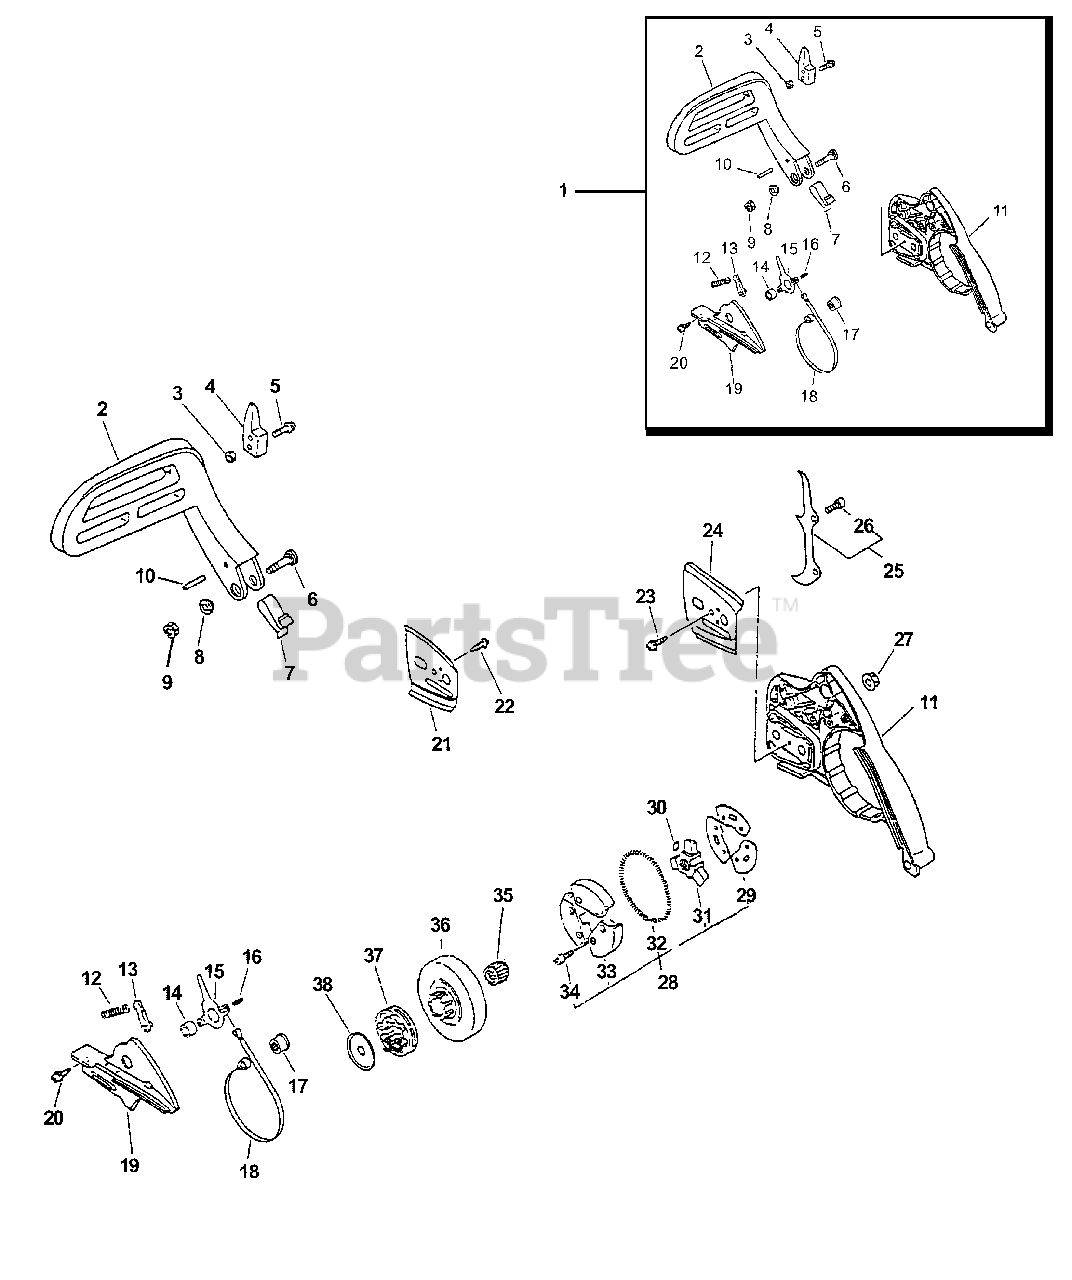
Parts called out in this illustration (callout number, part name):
1	CHAIN BRAKE ASSY
2	BRAKE LEVER ASSY
4	WEIGHT, BRAKE
5	SCREW 4×18
6	SCREW 5×30
7	SPRING
8	COLLAR 5.3×10×13×L5
9	NUT, LOCK M5
10	PIN 3×24
11	GUARD, SPROCKET
12	SPRING, COMPRESSION
13	STOPPER, BRAKE
14	WASHER 5.2×12×14
15	LEVER, BRAKE
16	PIN, SPRING 4×8.8
17	ADJUSTER, BRAKE
18	BAND, BRAKE
19	COVER, BRAKE
20	SCREW 4×10
21	PLATE, GUIDE - INNER
22	SCREW 4×6
23	SCREW 3×6
24	PLATE, GUIDE
25	SPIKE KIT, BUMPER
26	BOLT 5×12
27	NUT, FLANGE M8×1.25
28	CLUTCH ASSY
29	PLATE, CLUTCH
31	HUB, CLUTCH
32	SPRING, CLUTCH
33	SHOE SET, CLUTCH (3PCS)
34	BOLT 4×6
35	BEARING, NEEDLE
36	DRUM, CLUTCH
37	SPROCKET, 0.325 RIM
38	PLATE, CLUTCH
